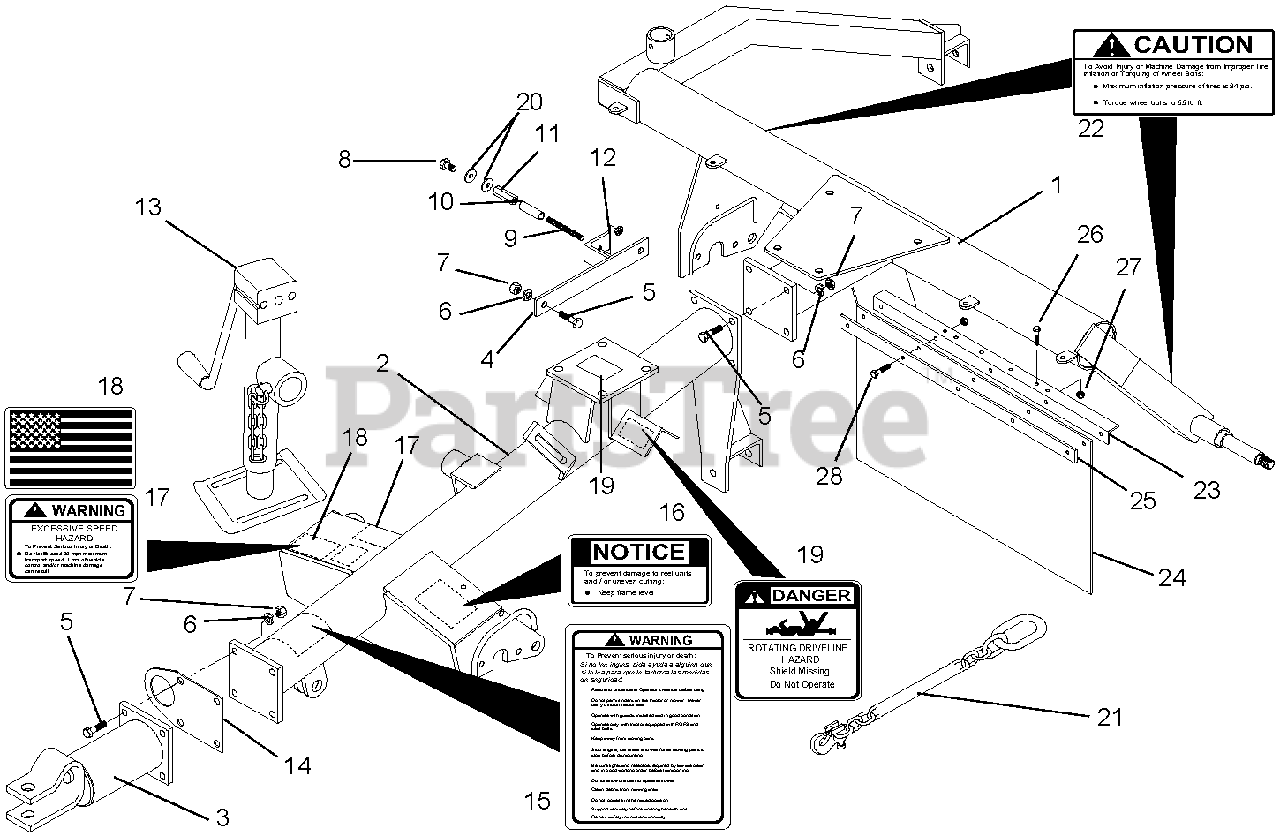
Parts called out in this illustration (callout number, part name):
1	Weldment, Mainframe
2	Tongue Assembly
3	Weldment, Clevis HItch
4	Weldment, Tongue Brace
5	Cap Screw, Hex Head .50-13 x 1.5
6	Washer, Lock .50
7	Nut, Hex .50 CP
8	Cap Screw, Hex Head .375 x .75
9	Stud, Belt Guard
11	Nut, Hex Coupler .375-16
12	Nut, Jam .375-16
13	Jack, Screw 5000-lb.
14	Holder, Hydraulic Hose
15	Decal, Warning
16	Decal, Notice
17	Decal, USA Flag
18	Decal, Warning
19	Decal, Danger
20	Washer, Flat .375 SAE
21	Chain, Safety Tow
22	Decal, Caution, 24 lb. Tire Pressure
23	Mounting Angle
24	Defector
25	Clamp Bar
26	Cap Screw, Hex Head, 5/16-18 x 1.0
27	Nut, Hex, Nyloc 5/16-18
28	Cap Screw, Hex Head 5/16-18 x 1.0
